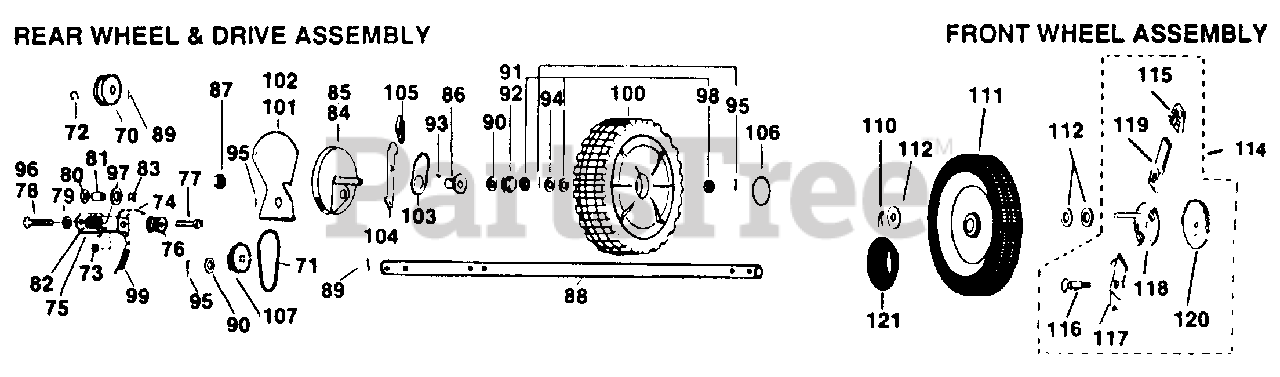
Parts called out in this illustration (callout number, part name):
70	Drive Pulley
71	V-Belt
72	Retaining Ring
73	Locknut 3/8-16
74	Belt Guide
75	Idbr Bracket
76	Idler Half
77	Shoulder Bolt
78	Flat Head Screw 1/4-20
79	Flatwasher
80	Flatwasher
81	Bushing-Idler Bracket
82	Spring-Idler Retum
83	Hex Locknut 1/4-20
84	RH Dust Cover Ass'y
85	LH Dust Cover Ass'y
86	Hub & Bearing
87	Hex Jam Nut 1"-14
88	Drive Axle
89	Roll Pin 3/16 x 1"
90	Flatwasher
91	LH Drive Gear
92	RH Drive Gear
93	Drive Pin (Round)
94	Flatwasher 1/2"
95	Cotter Pin 1/8 x 3/4"
96	Flat Head Screv 1/4-20
97	Flatwasher
98	Flatwasher
99	Spring-Drive
100	10- Wheel Assembly
101	RH SAC Plate
102	LH SAC Plate
103	Spring-Height Adjust
104	Lever-Height Adjust
105	Knob-SAC Lever
106	Hubcap
107	Pulley-Driven
110	Cotter Pin 1/8 x 3/4"
111	8" Wheel Assembly
112	Flatwasher 1/2"
114	Adjustor Ass'y
115	Knob-SAC Lever
116	Shoulder Bolt
117	Spring-Height Adj
118	Disc & Pin Ass'y
119	Lever-Height Adj
120	Inner Plate
121	Hubcap
